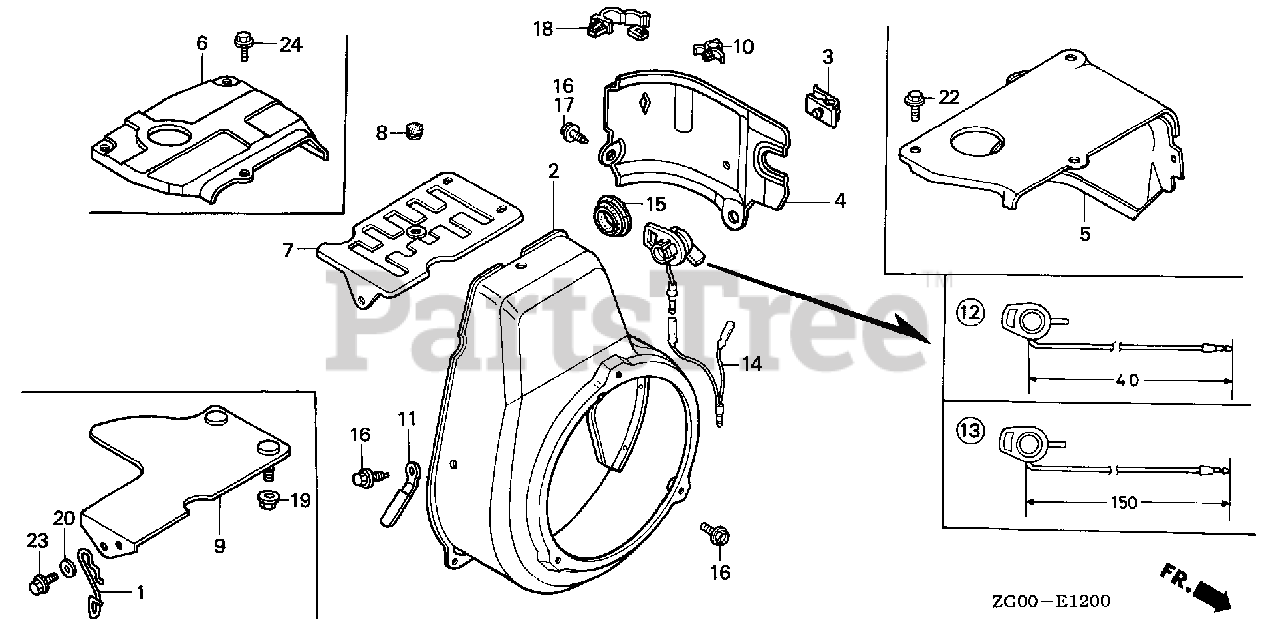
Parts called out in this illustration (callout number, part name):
2	COVER, FAN *R8* (BRIGHT RED)
12	SWITCH ASSY., ENGINE STOP
16	BOLT, FLANGE (6X12) (CT200)
17	BOLT, FLANGE (6X12) (CT200)
18	CLIP, TUBE (7MM)
